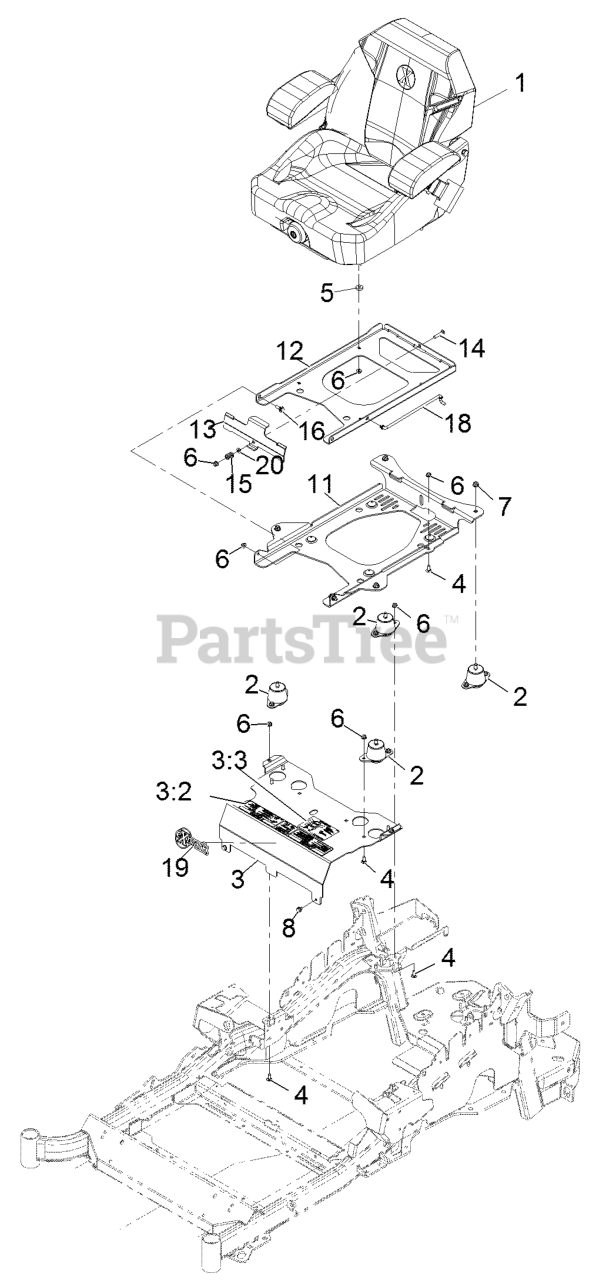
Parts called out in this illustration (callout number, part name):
1	KIT-SUSPENSION SEAT
2	ISOLATOR-SEAT
3	MOUNT-SEAT
3:2	DECAL-CONSOLE
3:3	DECAL-SERVICE AID
4	SCREW-CARR
6	NUT-HF, NI
7	NUT-HF, NI
11	PLATE-TILT, SEAT SUPPORT
12	PLATE-FRAME, SEAT
13	PLATE-LATCH, SEAT
14	BOLT-CARR
15	SPRING-COMPRESSION
16	SCREW-SHOULDER
18	ROD-PROP
20	WASHER-PLAIN
